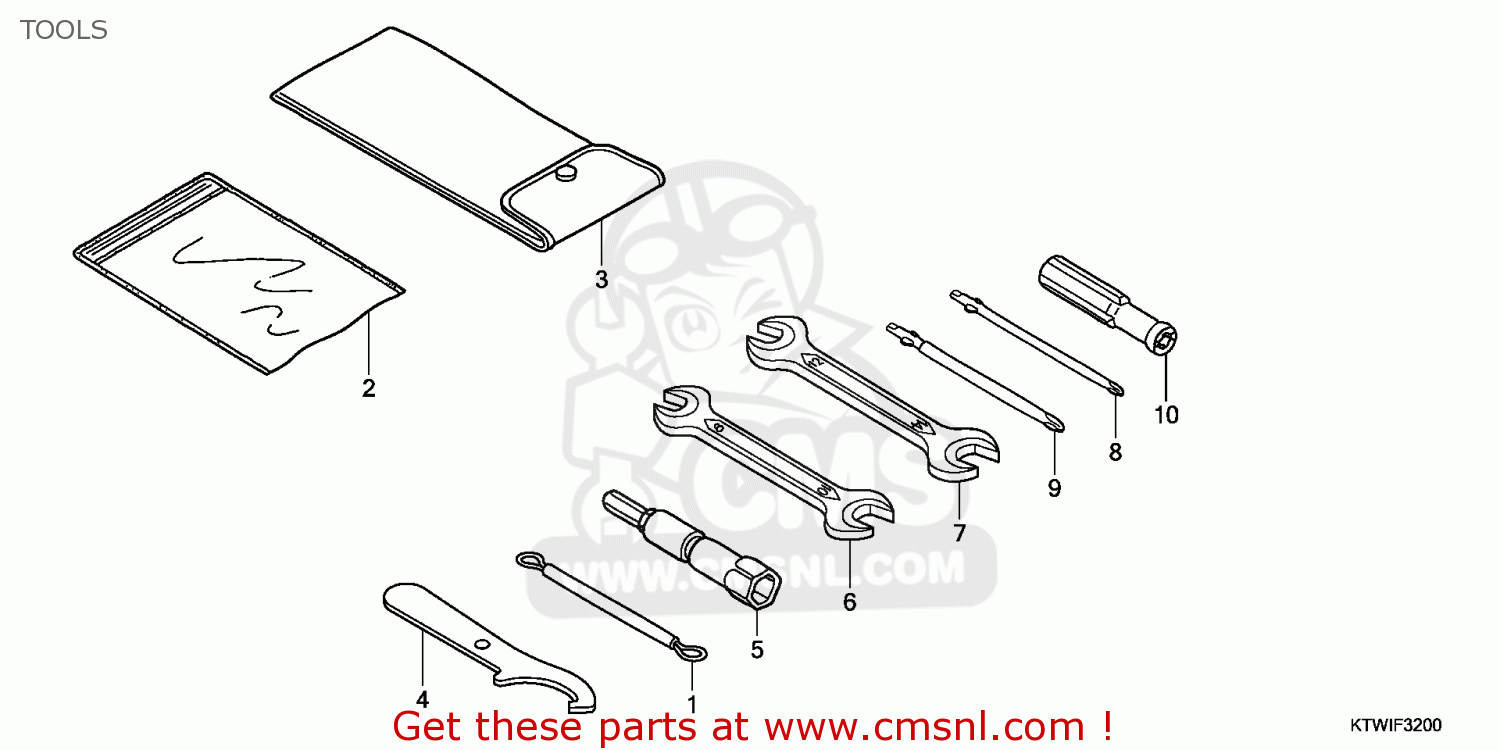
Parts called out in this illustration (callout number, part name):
1	WIRE,HELMET SET
2	BAG,SERVICE BOOK
3	TOOL,BAG,160MM
4	SPANNER,PIN
5	BOX WRENCH,P14
6	SPANNER,8X10
7	SPANNER 12X14
8	DRIVER
9	DRIVER
10	GRIP,SCREW DRIVER
